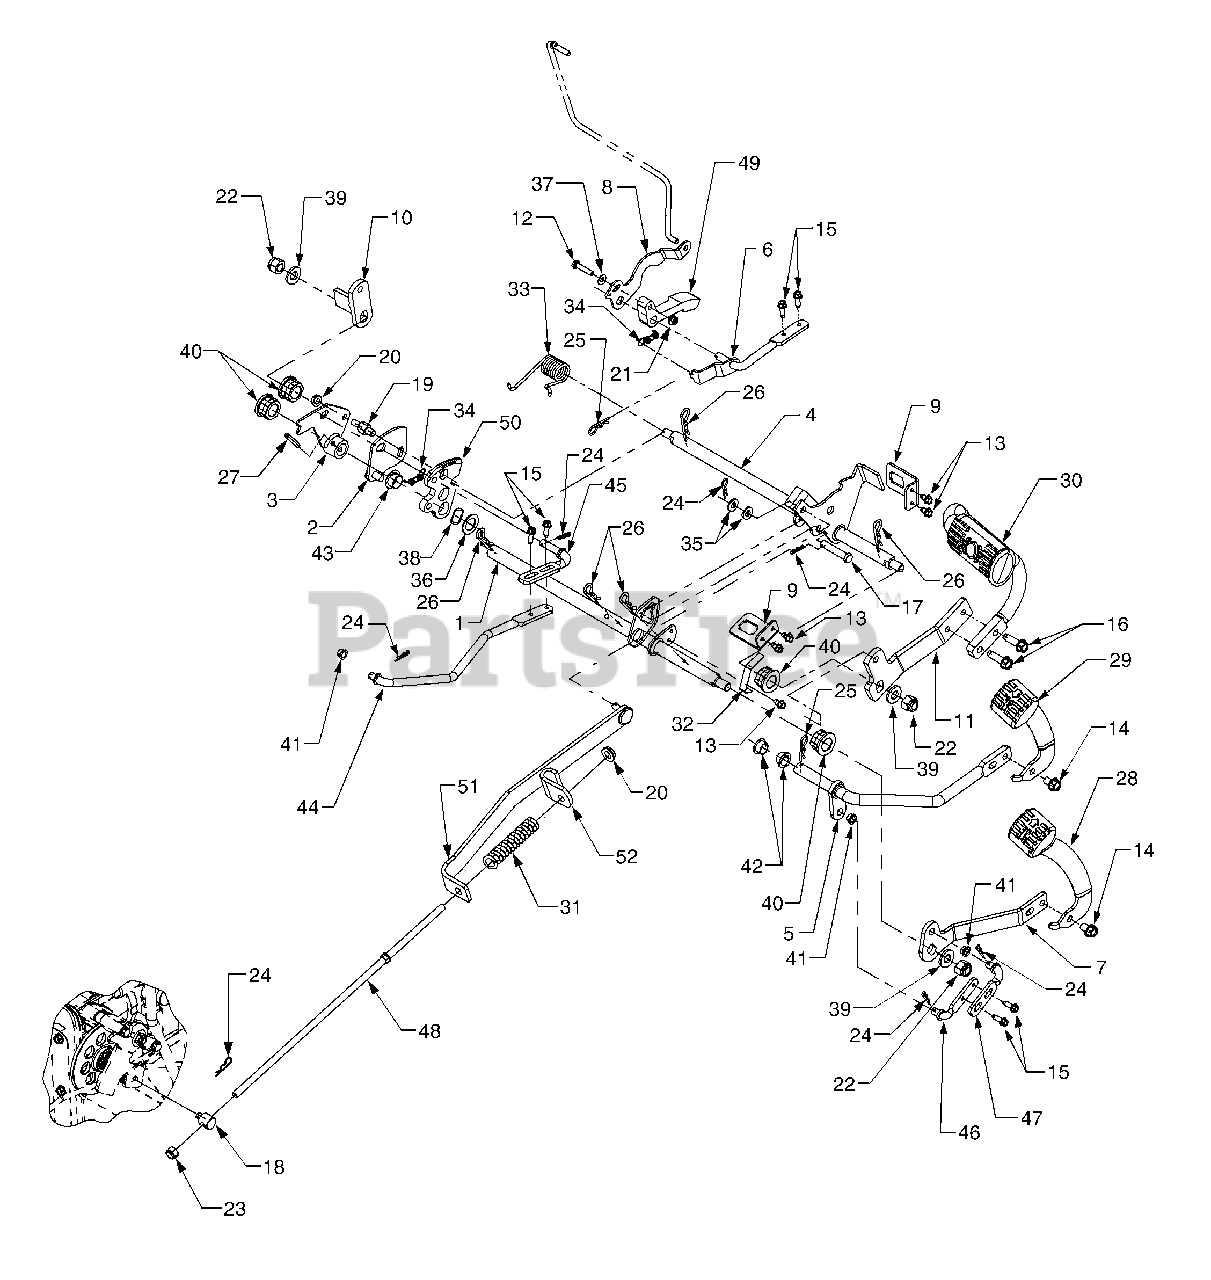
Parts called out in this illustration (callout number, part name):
1	Shaft Assembly, Pedal
2	Plate, Disengagement
3	0637 Cam, Clutch
4	Shaft Assembly, Brake
5	Shaft Assembly, Reverse
6	Rod Assembly, Cruise
7	Link, Pedal Mounting
8	Bracket, Rod Adjust
9	Bracket, Switch
10	Lever, Brake Diff Lock
11	Link, Brake Pedal
12	Screw, Hex Cap, 1/4-20 x 1.25 GR5
13	Screw, Hex Wash Hd Tapp 1/4-20 x .5
14	Screw, Hex Wash Hd Tapp 3/8-16 x .75
15	Screw, Hex Wash Hd Tapp 1/4-20 x .75
16	Screw, Hex Wash Hd Tapp 3/8-16 x 1.25
17	Pin, Clevis, 3/8 x 2.015
18	Ferrule, Adjust
19	Stud, Actuator
20	Nut, Hex Flange Lock, 5/16-18
21	Nut, Hex Flange Lock, 1/4-20
22	Nut, Hex Insert Lock, 1/2-20
23	Nut, Hex Insert Lock, 5/16-18
24	Pin, Internal Cotter
25	Pin, Internal Cotter
26	Pin, Internal Cotter
27	Pin, Spiral Spring, .25 x 1.5
28	Pedal, Forward
29	Pedal, Reverse
30	Pedal, Brake
31	Spring, Compression
32	Spring, No Cut Reverse
33	Spring, Torsion
34	Spring, Extension, .380 OD x 1.44
35	Washer, Flat, 344 x .688 x .065
36	Washer, Flat, .79 x 1.24 x .060
37	Washer, Flat, .25 x .62
38	Washer, Wave, .785 x 1.0 x .012
39	Washer, Flat, .531 x 1.06 x .134
40	Bearing, Hex Flange
41	Bearing, Flange
42	Bearing, Flange
43	Bearing, Flange
44	Rod, Rear Control
45	Rod, Front Control
46	Rod, Rear Connecting
47	Rod, Front Connecting
48	Rod, Brake
49	Cruise Latch
50	Plate, Cruise
51	Link Assembly, Brake
